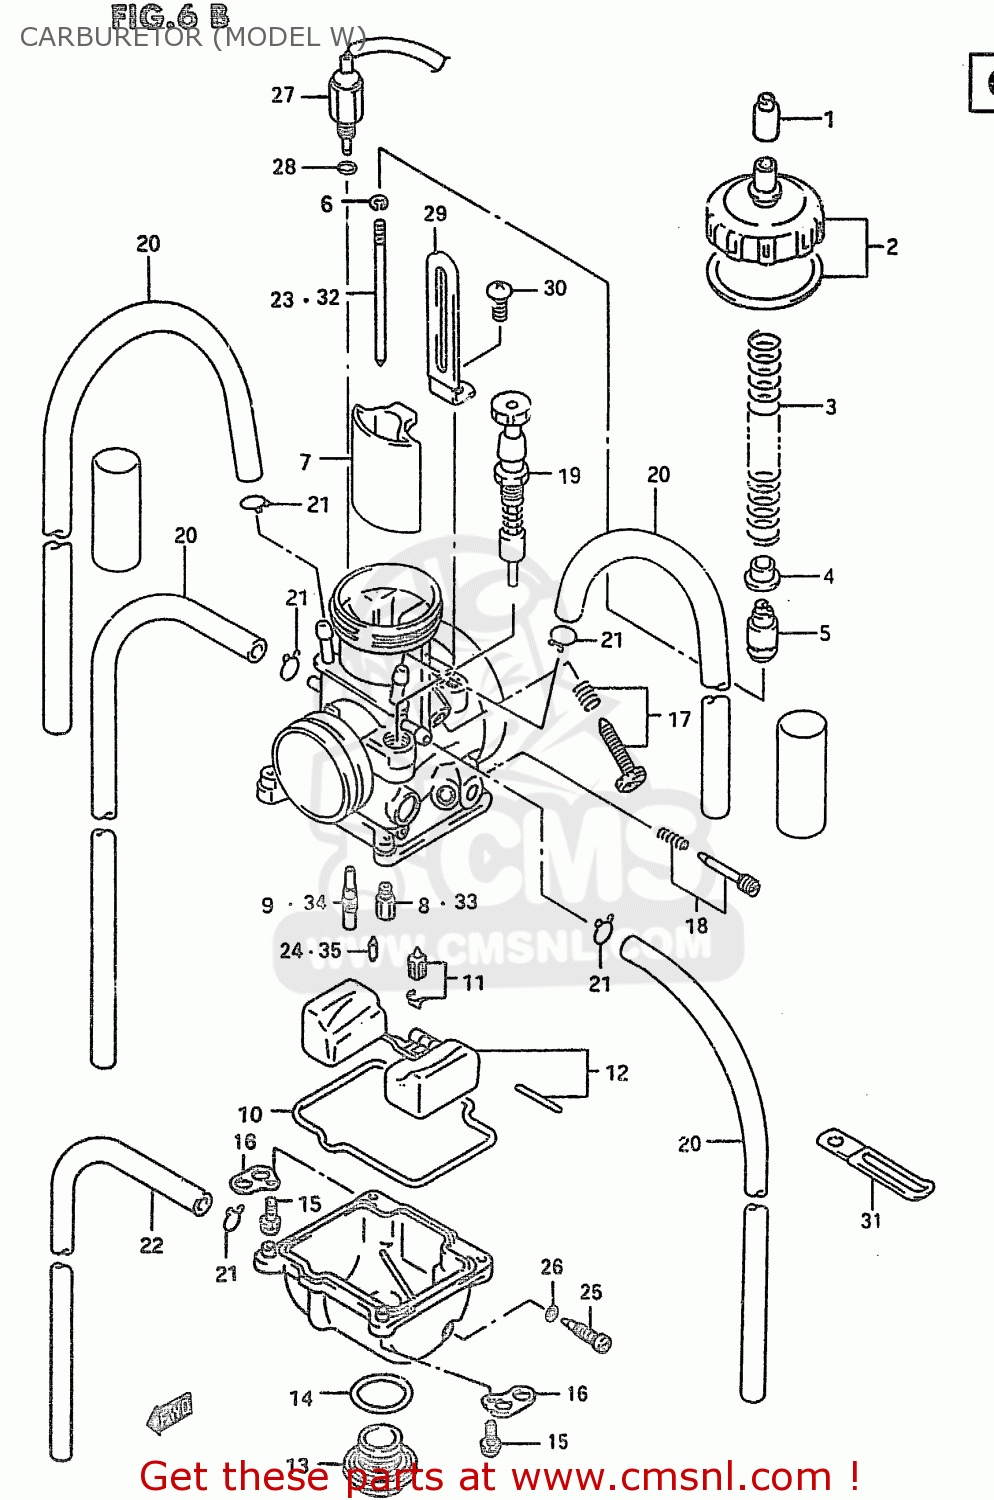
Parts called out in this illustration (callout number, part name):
1	CAP,CARBURETOR
2	CAP SET,TOP
3	SPRING,THROTTLE VALVE
4	COLLAR,THROTTLE VALVE
5	HOLDER,CABLE
6	CLIP,NEEDLE
7	VALVE,THROTTLE
8	JET,MAIN(162)
9	JET,PILOT(45)
10	GASKET,FLOAT CAHMBER
11	VALVE SET,FLOAT
12	FLOAT SET
13	BOLT,DRAIN
14	O RING
15	SCREW
16	PLATE
17	SCREW SET,STOP
18	SCREW SET,AIR
19	STARTER VALVE
20	HOSE(4X7X620)
21	CLIP
22	HOSE(3.5X6.5X600)
23	NEEDLE(N1EI)
24	JET,POWER(60)
25	SCREW,DRAIN
26	O RING
27	SOLENOID ASSEMBLY
28	O RING
29	CLAMP
30	SCREW
31	CLAMP(L:45)
32	NEEDLE(N0ZG)
33	JET,MAIN(150)
34	JET,SLOW(35)
35	JET,POWER(50)
